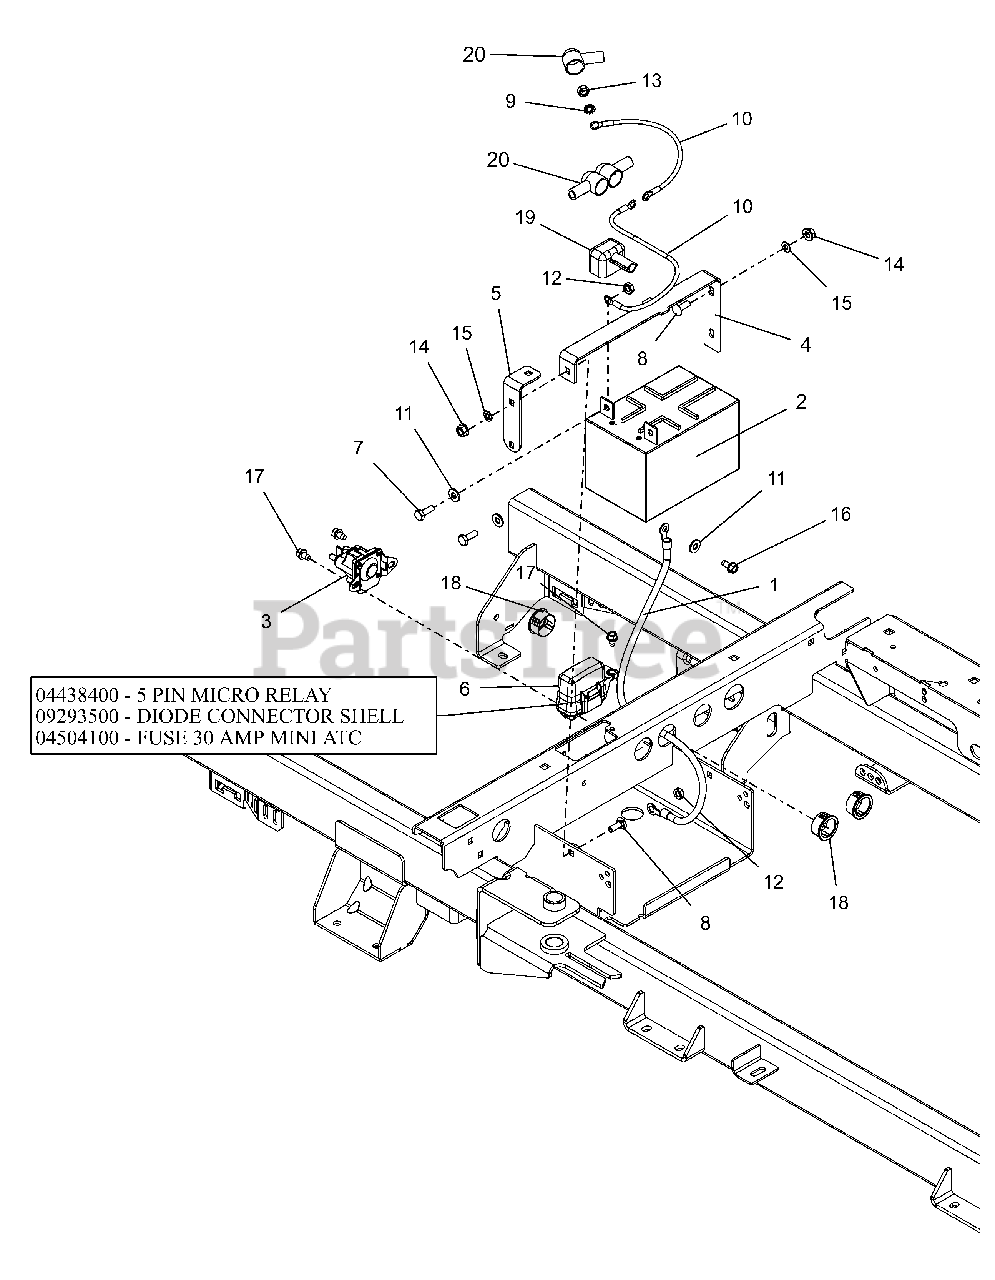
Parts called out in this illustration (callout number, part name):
1	CABLE-NEGATIVE BATTERY 24.00"
2	BATTERY, 12V 12A-190CCA
3	SOLENOID, STARTER (SEALED)
4	BRKT, BATTERY HOLD-DOWN
5	BRKT, BATTERY HOLD DOWN
6	HARNESS, WIRE-4POS KEY IKON/ZT
6	RELAY,MICRO5 TERML W/RESISTOR
6	DIODE, CONNECTOR SHELL
6	FUSE,30 AMP MINI-ATC
7	@BLT-HEX .25-20X.75 GR5 YWZC
8	@BLT-RDHDSQNK .25-20X.75 G5YZ
9	@WSHR-LK-EXT.262X.502X.026YWZC
10	CABLE,POS W/2 1/4 RING 15.0 LG
11	@WSHR-FL-STL.281X.62X.065 YWZC
12	NUT-KEPS .250-20 ZCC
13	@NUT-HEX .25-20 YWZC
14	@NUT-LK-TOP-FLG .25-20 YWZC
15	NUT-PUSH .25X.50 O.D.
16	SCR-TAP .25-20X.50 HWH TR YWZ
17	@SCR-TAP .25-20X.37 HWH YWZ TR
18	BSHG, PANEL SNAP .937X1.11X.56
19	INSULATOR
20	BOOT, EYELET TERMINAL
